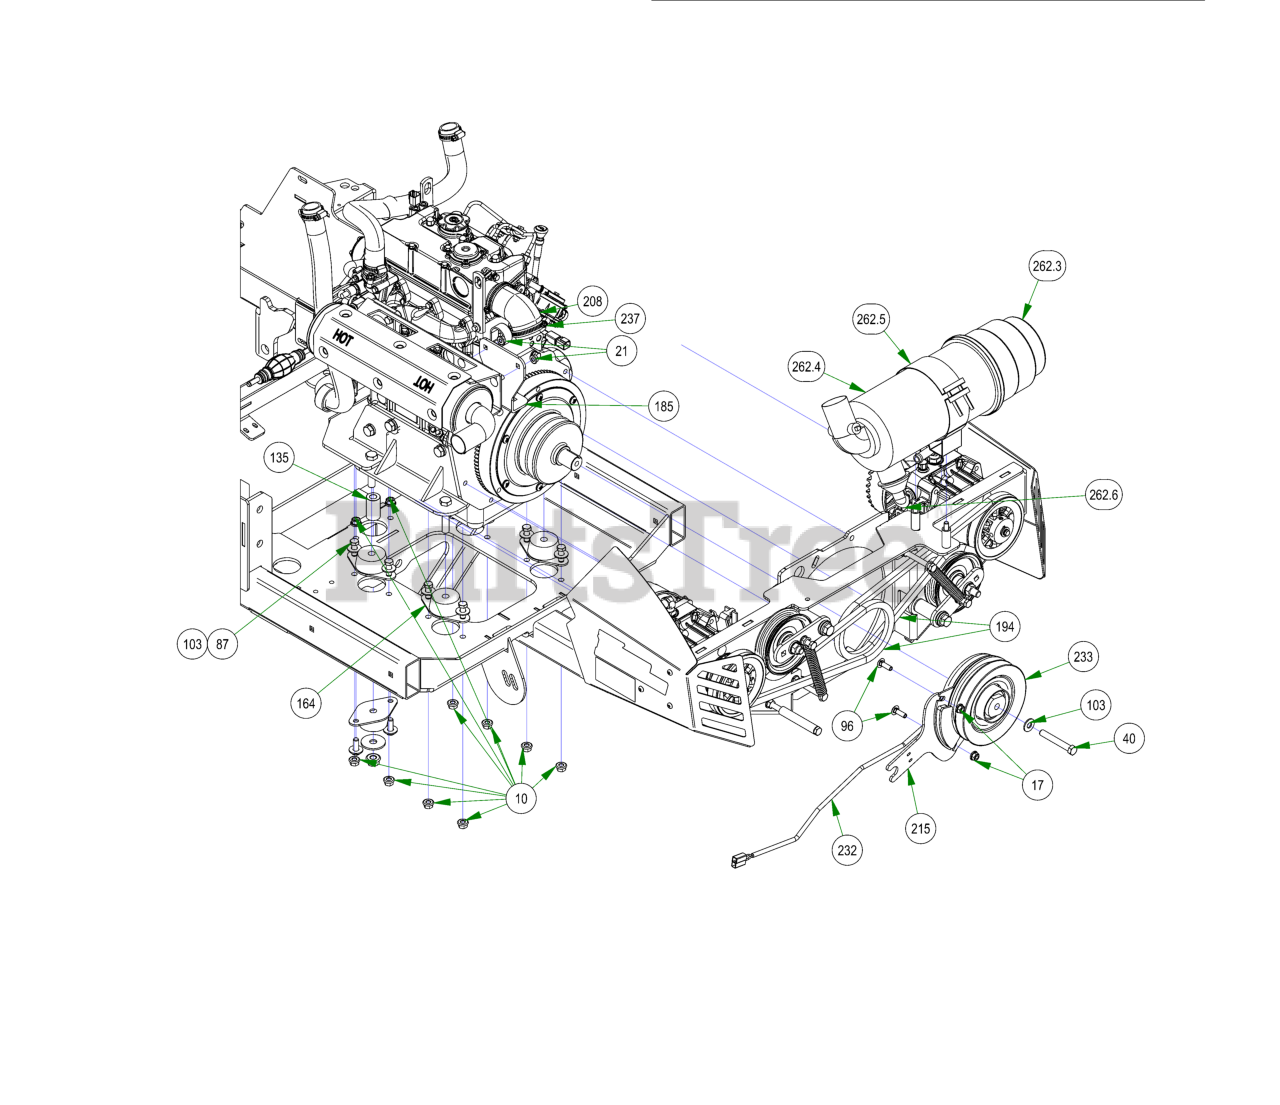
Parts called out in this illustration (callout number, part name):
10	3/8-16 NYLON INSERT FLANGE LOCKNUT (GR.F) ZINC
17	5/16-18 NYLON INSERT FLANGE LOCKNUT ZINC
21	5/16-18 HEX SERRATED FLANGE NUT HARD/ZINC
40	7/16-20x3” Hex Bolt GR 8 W/ Patch
44	5/16-18 X 2-1/4 HEX CAP SCREW (GR.5) ZINC
74	1/2-13 X 4 HEX CAP SCREW (GR.8) ZINC YELLOW
87	3/8-16 X 1 GR 5 Hex Bolts Zinc
98	M12-1.25 X 30MM DIN 961 HEX TAP BOLT (CL 8.8) ZINC
103	3/8 FLAT WASHER USS (1" OD) ZINC
128	.380 ID X .625 OD X 1.500 LGTH 2019 OUTLAW BRAKE HANDLE SPACER ZINC
135	1 3/4" Pulley Spacer
164	Rubber Compression Mount
168.1	5" Pump Pulley
168.2	5/16-24 X 1/2 SOCKET SET SCREW KNURLED CUP POINT
185	2019 Diesel Muffler Bracket
194	2020 Renegade Pump Belt, 42.99"
208	2019 Diesel Air intake Hose
215	2019 Outlaw Renegade Clutch Bracket
232	Clutch Pigtail
233	Clutch for Diesel/Vanguard
237	2-1/2" Hose Clamp
262	Enginaire Canister VLR-Complet
262.1	Diesel Air Filter- Outer
262.2	Diesel Air Filter- Inner
262.3	Enginaire Air canister cap
262.4	Canister for All Diesel Models
262.5	Mounting Bracket For Diesel Air Filter
262.6	Debris Plug-Enginaire Filter
